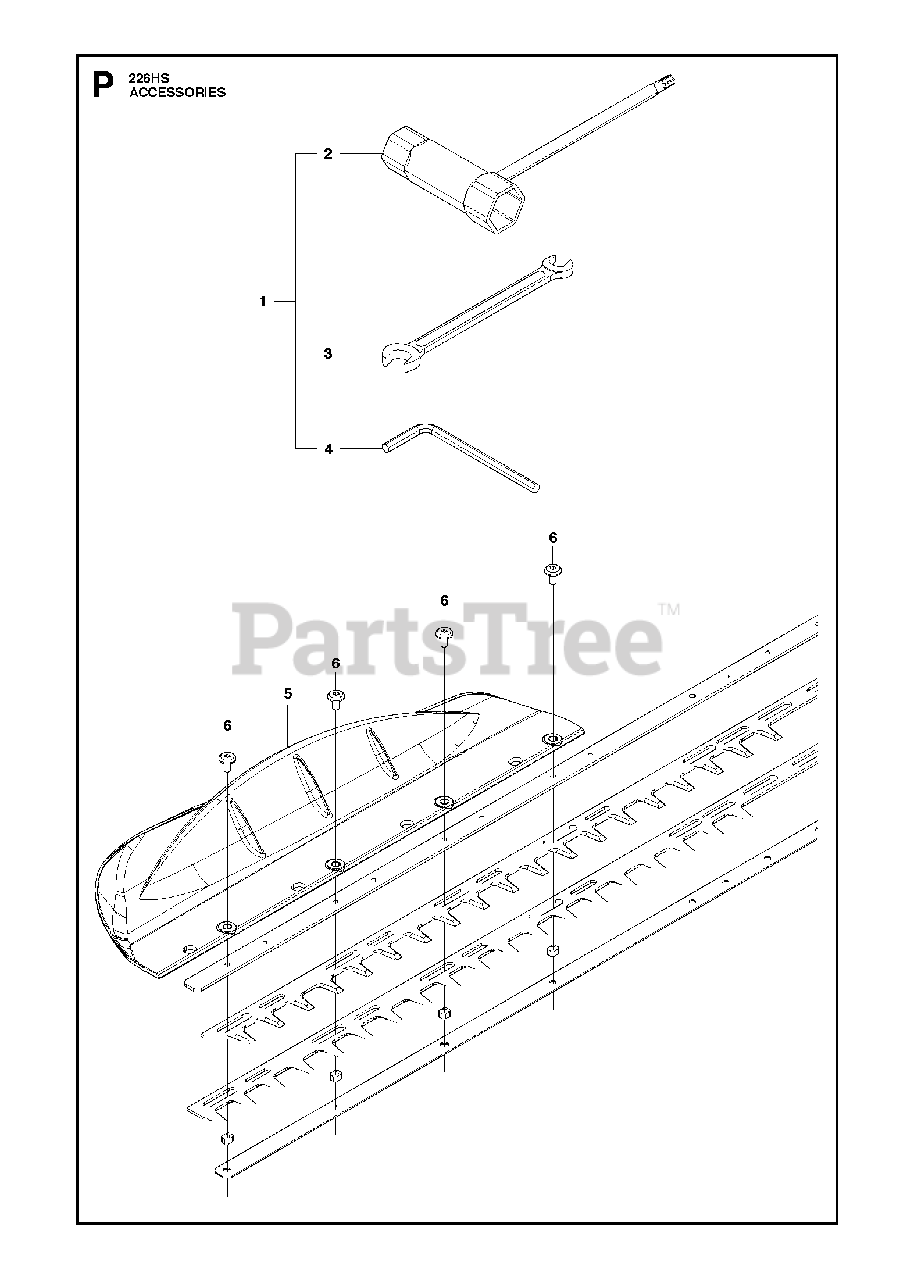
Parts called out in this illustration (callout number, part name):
2	SOCKET
3	SPANNER
4	WRENCH
